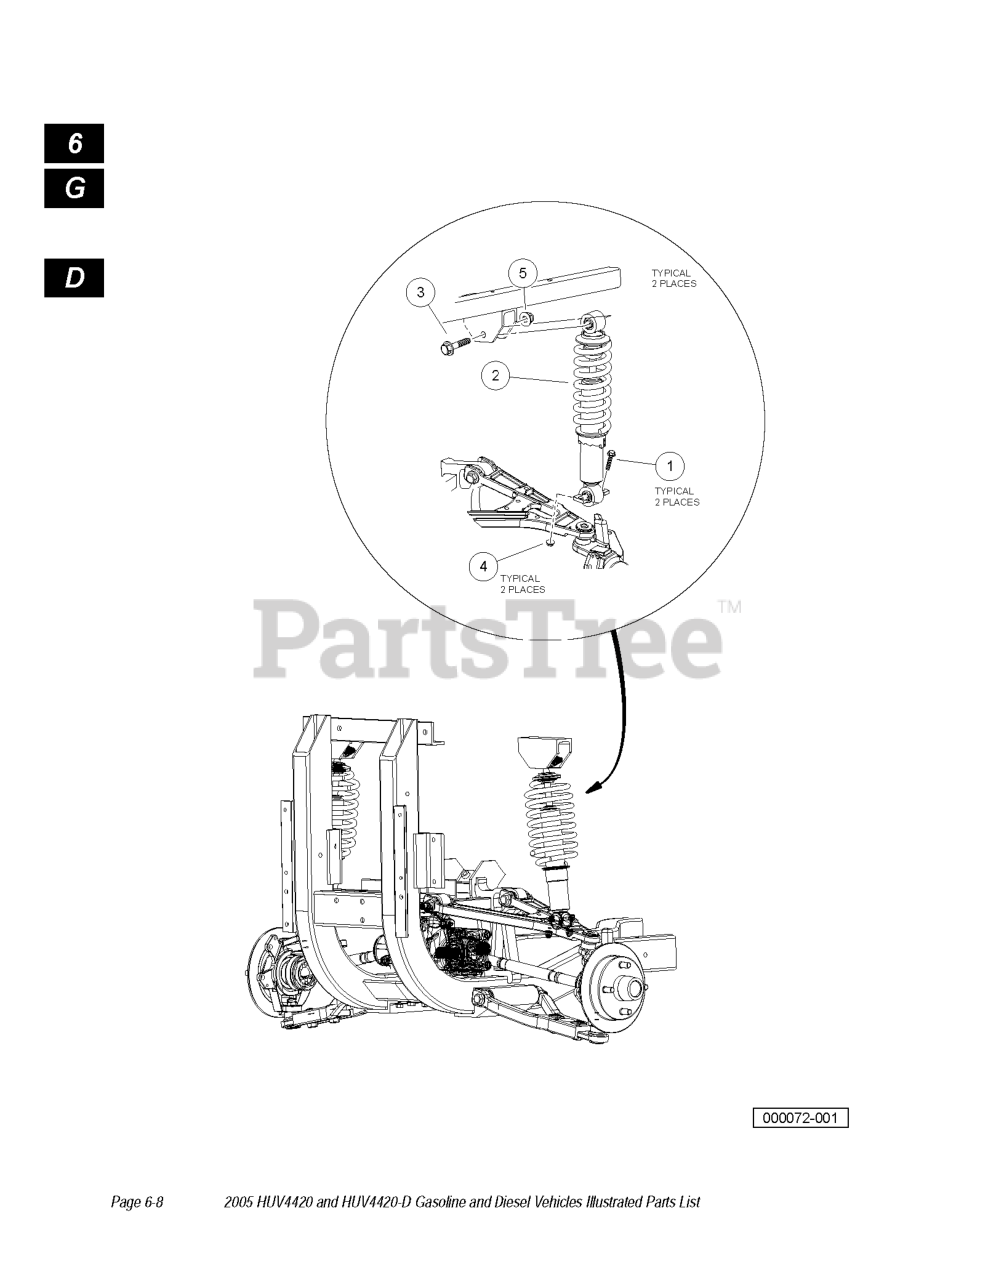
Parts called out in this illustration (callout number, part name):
1	BOLT, FLANGE HD, M8 X 40.0
2	SHOCK, COIL OVER, FRONT HD
3	BOLT, FLG, M12X1.75X70
4	LOCK NUT, FLG M8 X 1.25 NYLON
5	NUT FLG, M12X1.75, NYLON GR 10
